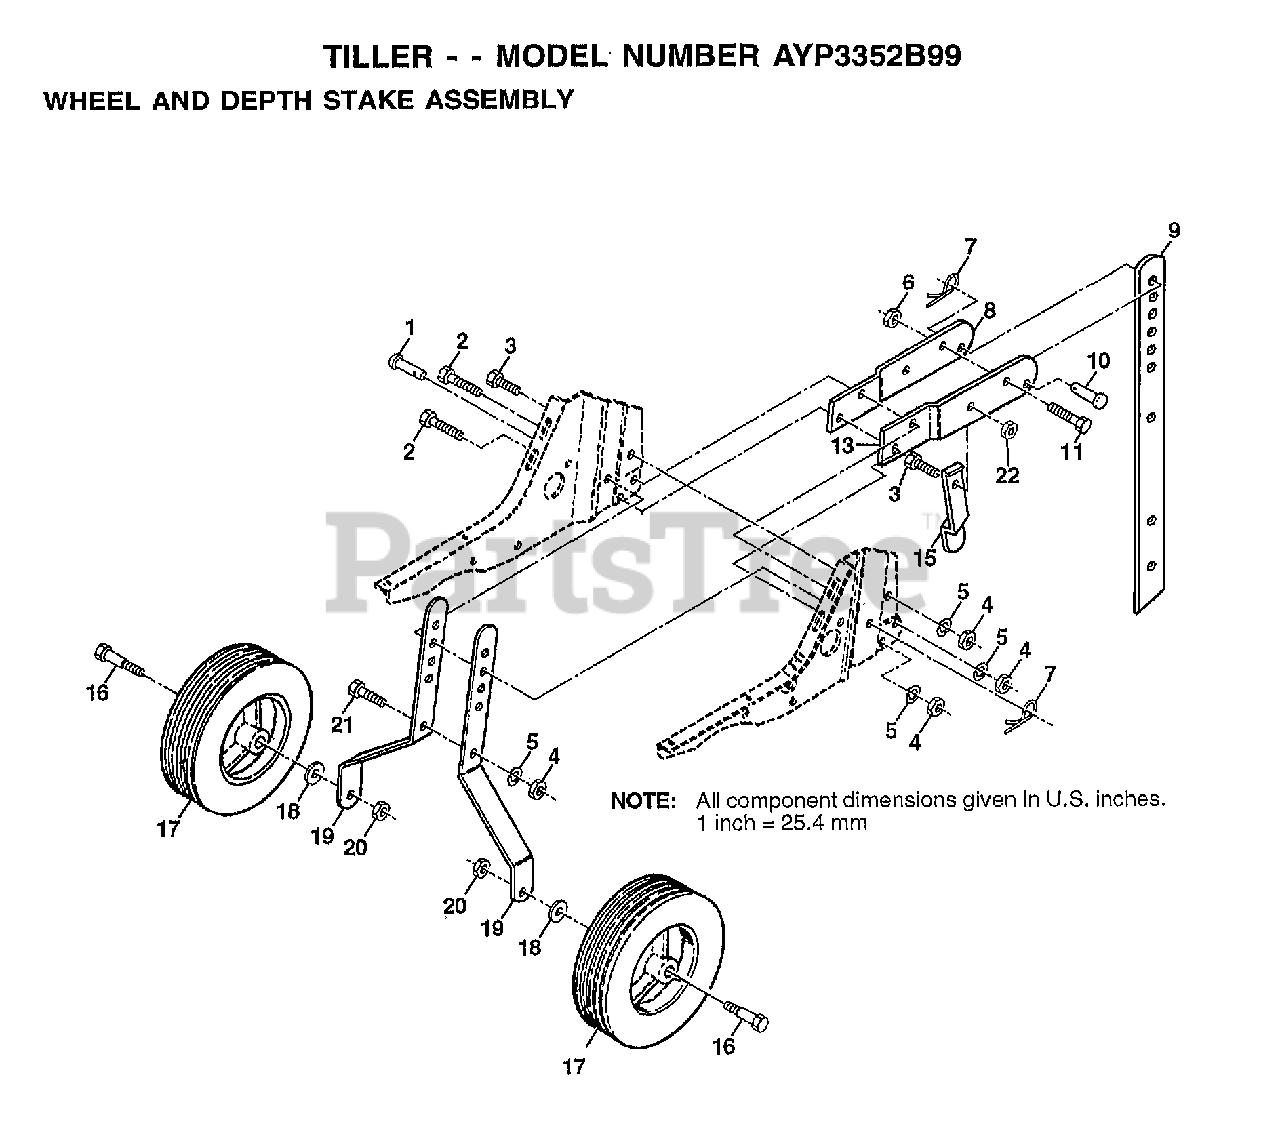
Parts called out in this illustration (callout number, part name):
1	DRILLED RIVET RT
3	BOLT
4	NUT.HEX.5/16-18
5	LOCKWASHER
6	NUT
7	SPRING.RETAINER
11	BOLT
15	STAKE SPRING TI
16	BOLT SHOULDER
18	WASHER
22	NUT
